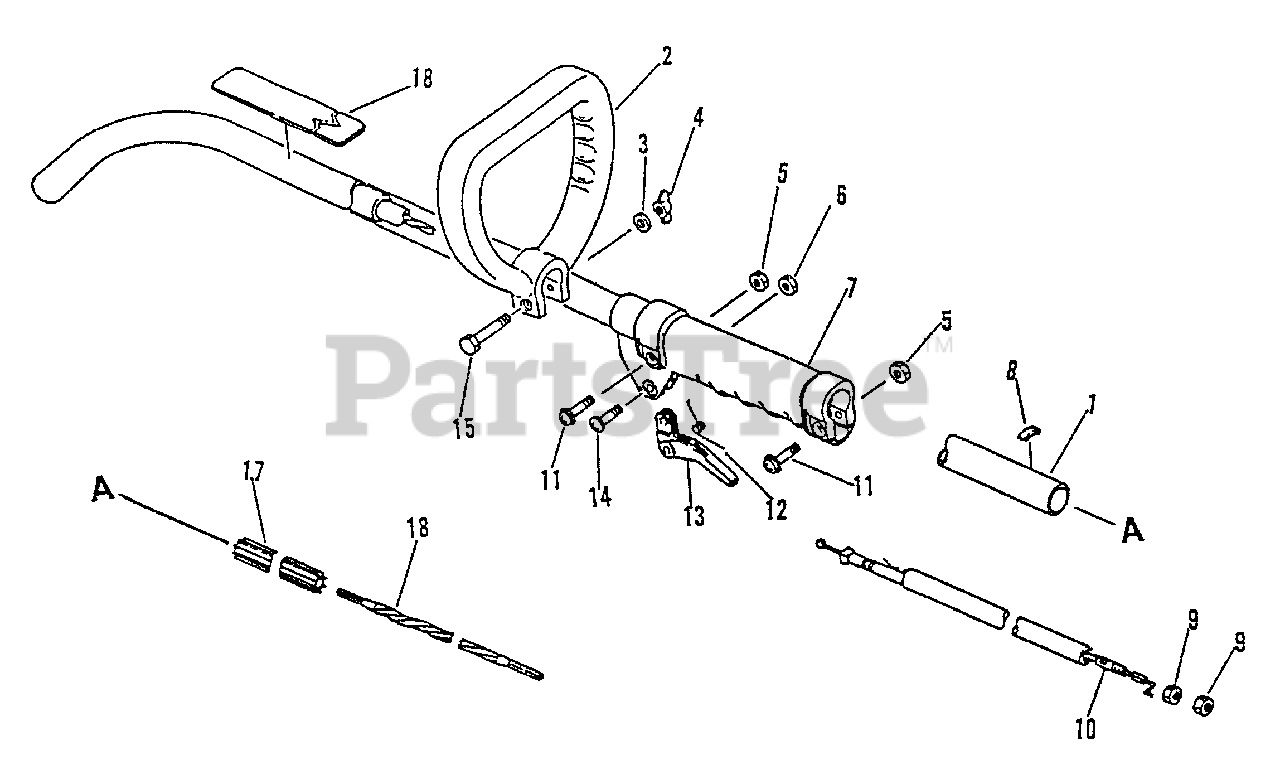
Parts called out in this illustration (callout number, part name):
1	MAIN PIPE ASSY
2	HANDLE - FRONT
3	WASHER - 6
4	WINGNUT - 6
6	LOCKNUT - 5
7	GRIP, HANDLE
8	LABEL - ALIGNMENT
10	CABLE, THROTTLE
11	SCREW - 5X25
12	SPRING, TRIGGER
13	TRIGGER, THROTTLE
14	SCREW - 5X30
15	BOLT - 6X40
16	DRIVESHAFT - FLEXIBLE
17	LINER - FLEXIBLE
18	LABEL - CAUTION
